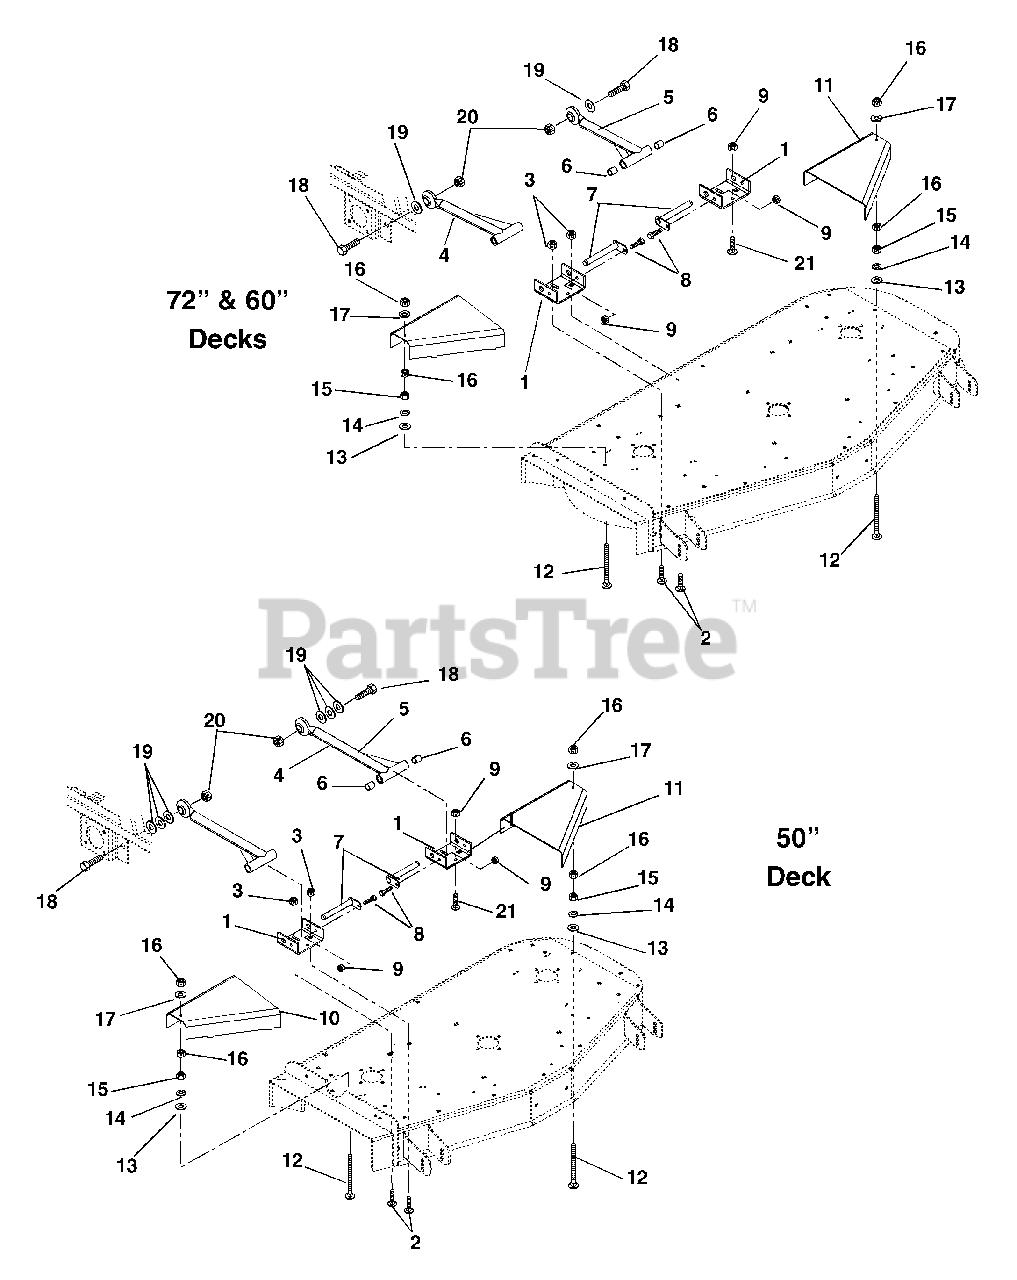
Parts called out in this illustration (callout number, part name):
1	Bracket, Mower Mounting (Rear)
2	Bolt-Round Head Square Neck .50-13 x 1.00 Grade 2
3	Nut-Locking-Center .50-13
4	Assembly, Mower Mounting Arm
5	Weldment-Mower Mounting Arm
6	Bearing .75 x .875 x 1.00
7	Weldment, Mower Mounting Pin
8	Bolt-Hex .38-16 x .75 Grade 5
9	Nut-Locking-Center .38-16
10	Guard, Pulley Right Hand (60" Deck)
10	Guard, Pulley Right Hand (50" Deck)
10	Guard, Pulley Right Hand (72" Deck)
11	Guard, Pulley Left Hand (60" Deck)
11	Guard, Pulley Left Hand (50" Deck)
11	Guard, Pulley Left Hand (72" Deck)
12	Bolt-Round Head Square Neck .31-18 x 3.50
13	Washer-Flat-Steel .344 x .688 x .065
14	Washer-Locking .31 x .078
15	Nut-Hex .31-18
16	Nut-Locking-Center .31-18
17	Washer-Flat-Steel .438 x 1.00 x.083
18	Bolt-Hex .875-9 x 2.75 Grade 5
19	Washer-Flat-Steel .875 x 1.50 x .120 (60" & 72" Deck)
19	Washer-Flat-Steel .875 x 1.50 x .120 (50" Deck)
20	Nut-Locking-Center .875-9
21	Bolt-Round Head Square Neck .38-16 x 1.00 Grade 5 (60" & 72" Deck)
21	Bolt-Round Head Square Neck .38-16 x 1.00 Grade 5 (50" Deck)
